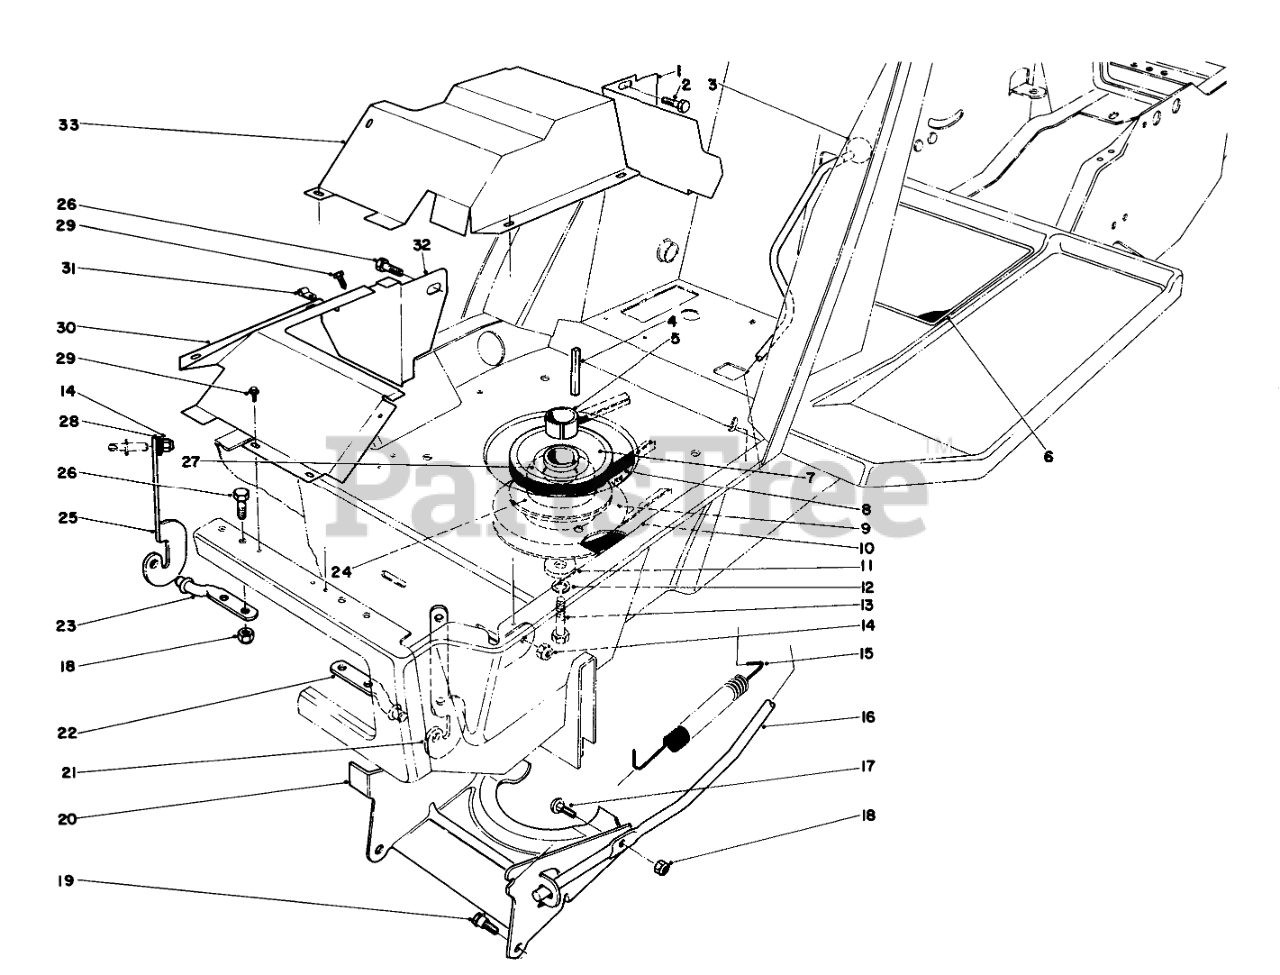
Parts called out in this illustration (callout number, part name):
1	EXH SHIELD SUPT B
2	SCREW-HH
4	KEY-SQUARE
5	PULLEY SPACER
6	OPERATION DECAL
7	TOP SHEAVE
8	V BELT
9	CLUTCH KIT W/O
10	V-BELT, ENG/DECK
11	WASHER
12	WASHER-LOCK
13	SCREW-HH
14	NUT-LOCK, CONE
15	TRACTION SPRING
16	Engagement Lever
17	Bolt
18	NUT-LOCK, CONE
19	SCREW-SHOULDER
20	CLUTCH ACTUATOR R
21	L.H. HINGE BRACKET
22	LH HOOD HINGE PIN
23	RH HOOD HINGE PIN
24	CLUTCH PLATTER
25	RH HINGE BRKT
26	SCREW-HH
27	SPRING WASHER
28	SCREEN SUPT BRKT
29	SCREW-HWHTF
30	Heat Shield
31	CABLE CLAMP
32	Support Heat Shield
33	HEAT SHIELD WA B
